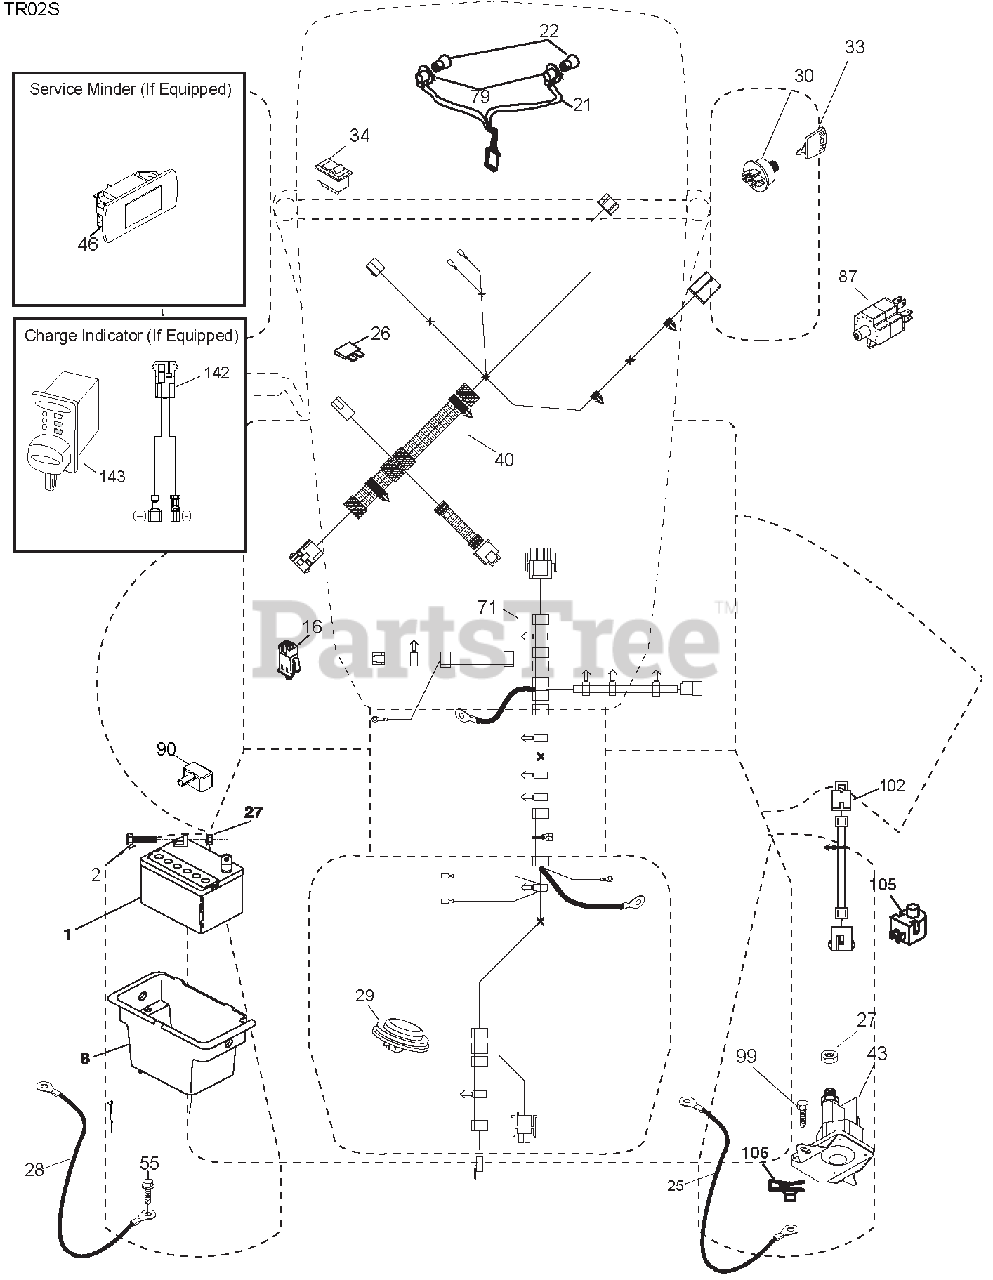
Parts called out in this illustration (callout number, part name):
1	BATTERY.12.VOLT.28.AMP.WET
2	BOLT.HEX.HD.1/4-20UNC X 3/4
8	BOX.BATTERY.MNT.REAR.LT.TEX.BL
16	SWITCH.INTERLOCK.NONO.GRAY
21	HARNESS ASM.LIGHT.22"(4152J)
22	BULB.LIGHT.#1156
25	CABLE STARTER 6 G4. BL/RED14.5
26	FUSE.20 AMP.
27	Nut, Keps Hex 1/4-20 unc
28	CABLE.BLACK.22"REAR BATT.TEX
29	SWITCH.SEAT.DELTA.OPC.9LB.
30	SWITCH.IGN.DLTA.P-IN.ROS
33	KEY/CHAIN.BLISTER PACK.GEN.USA
34	SWITCH.LIGHT/RESET.B/B/RED.
40	HARNESS.IGN.DASH
43	SOLENOID.W/BRASS PLUNGER.2005
46	GUAGE.SERVICE.MINDER
55	SCREW.5/16-18X3/4.SMGML.TAP/R
71	HARNESS.IGN.CHASSIS
79	SOCKET ASM.BULB.TWISTLOCK
87	SWITCH.INTRLCK.CLUTCH.CABLE.TX
90	COVER TERMINAL BATTERY FR. TEX
102	HARNESS.PIGTAIL
105	SWITCH.REVERSE.TT.PEDAL CONTRO
